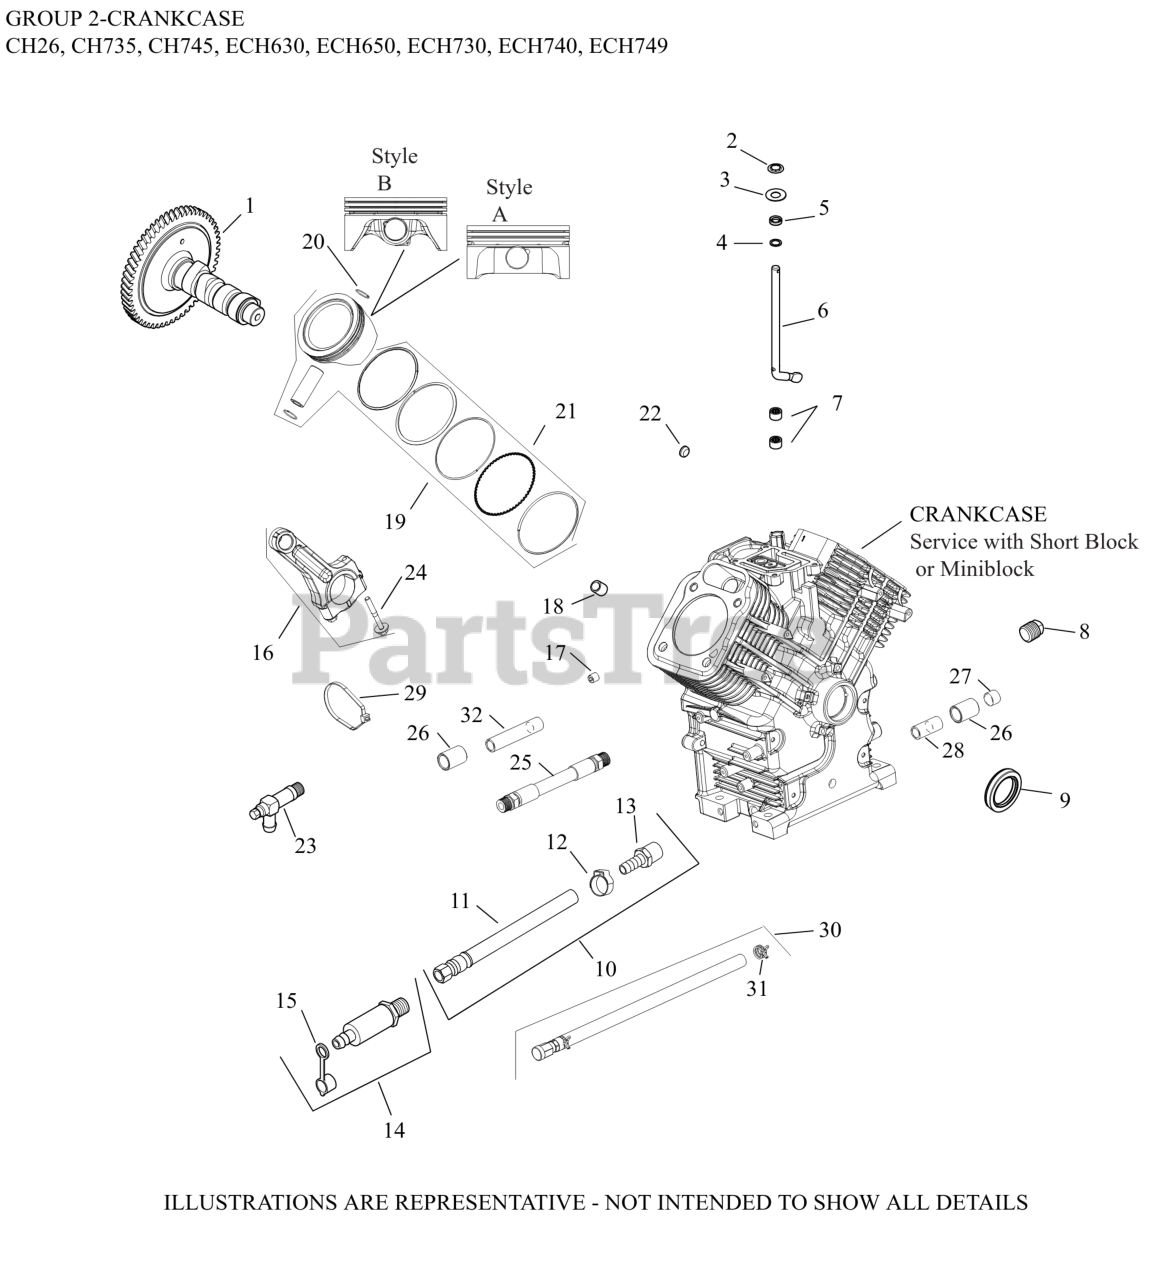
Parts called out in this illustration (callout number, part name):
1	KIT, CAMSHAFT
2	RETAINER, RING
3	WASHER, FLAT 9 MM
4	WASHER, FLAT 11/32"
5	SEAL, GOVERNOR CROSS SHAFT
6	SHAFT, GOVERNOR CROSS
8	PLUG, SQ HD PIPE 3/8"
9	SEAL, OIL (HELIX LIP)
16	ROD, ASSEMBLY CONNECTING
18	PIN, LOCATING
19	KIT,PSTN/RNG STYLE A(STD)(#2587406S)
19	KIT,PSTN/RNG STYLE A(.08)
19	KIT,PSTN/RNG STYLE A(.25)USE 2587411-S
19	KIT,PSTN/RNG STYLE A(.50)(#2587404S)
19	KIT,PSTN/RNG STYLE B(STD)
19	KIT,PSTN/RNG STYLE B(.08)
19	KIT,PSTN/RNG STYLE B(.25)
19	KIT,PSTN/RNG STYLE B(.50)
20	RETAINER, PISTON PIN
21	RING DISC USE PISTON ASSY PER SPEC
21	RING SET(.08)STYLE A-1.5mm Tp RING THICK
21	RING SET(.25)STYLE A-1.5mm Tp RING THICK
21	RING SET(.50)STYLE A-1.5mm Tp-(#DSC)
21	RING SET(STD)STYLE B-1.2mm Tp RING THICK
21	RING SET(.08)STYLE B-1.2mm RING THICK
21	RING SET(.25)STYLE B-1.2mm Tp RING THICK
21	RING SET(.50)STYLE B-1.2mm Tp RING THICK
22	PLUG, CUP
24	KIT, ROD BOLTS-(#25086677S)
